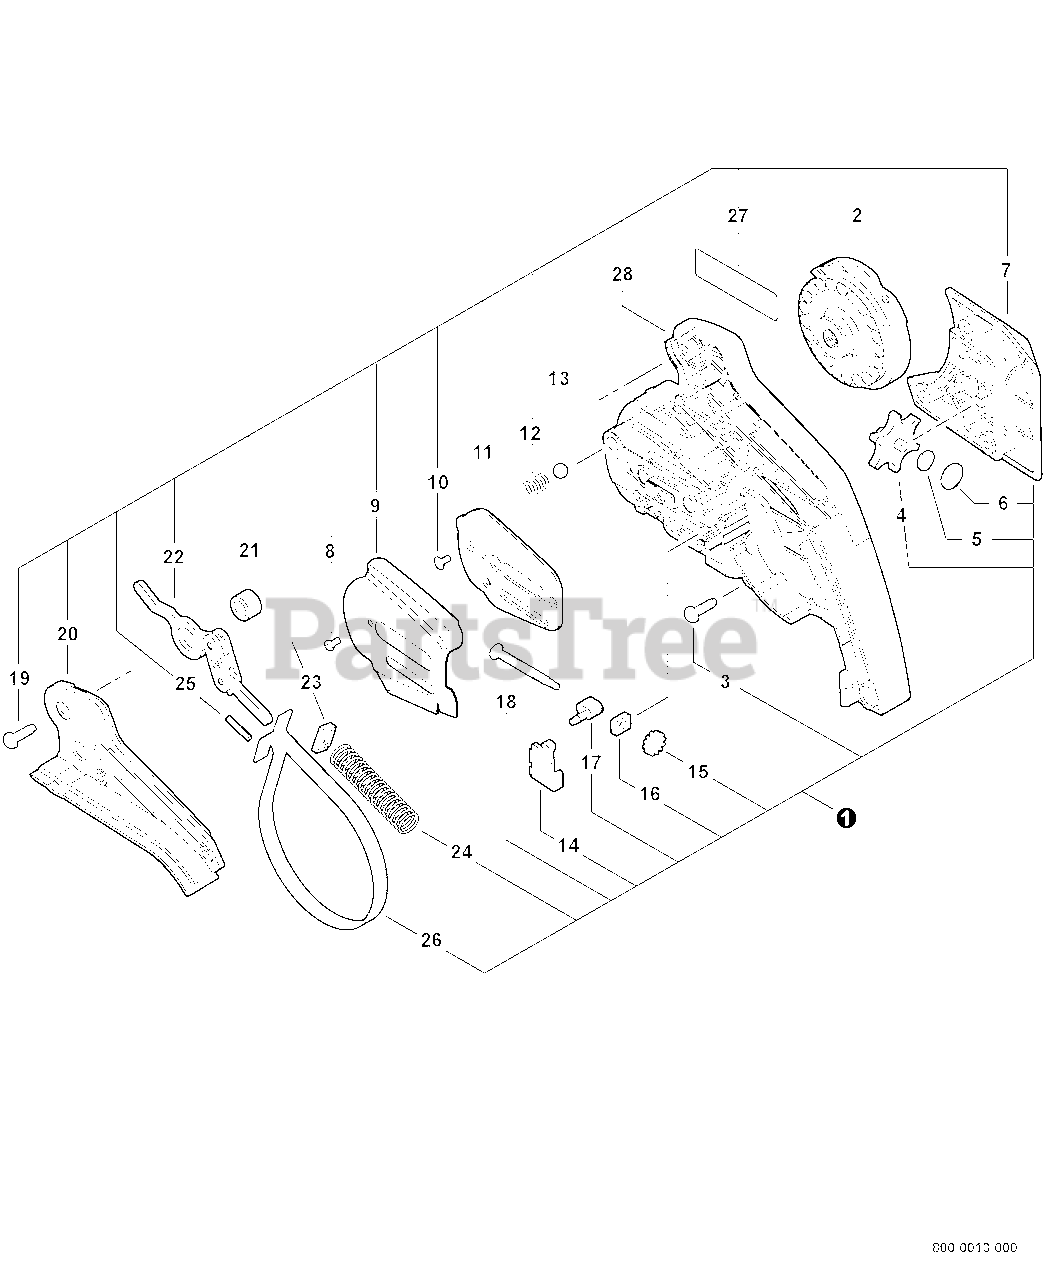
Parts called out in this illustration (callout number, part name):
1	CHAIN BRAKE ASSY
2	LOCK, COVER
3	SCREW - 4X12 -- TAPPING
4	DIAL, TENSION
5	WASHER - SPRING
6	WASHER - 5
7	COVER, DIAL
8	SCREW - 3X6
9	PLATE, GUIDE - OUTER
10	SCREW - 3
11	COVER, TENSIONER
14	COVER, DUST
15	GEAR - SPUR
17	TENSIONER, CHAIN
18	SCREW, TENSIONER
19	SCREW - 4X12 -- TAPPING
20	COVER, BRAKE
21	SPACER - 8
22	CONNECTOR, BRAKE
25	PIN - SPRING
26	BAND, BRAKE
27	LABEL - ECHO
28	GUARD, SPROCKET
